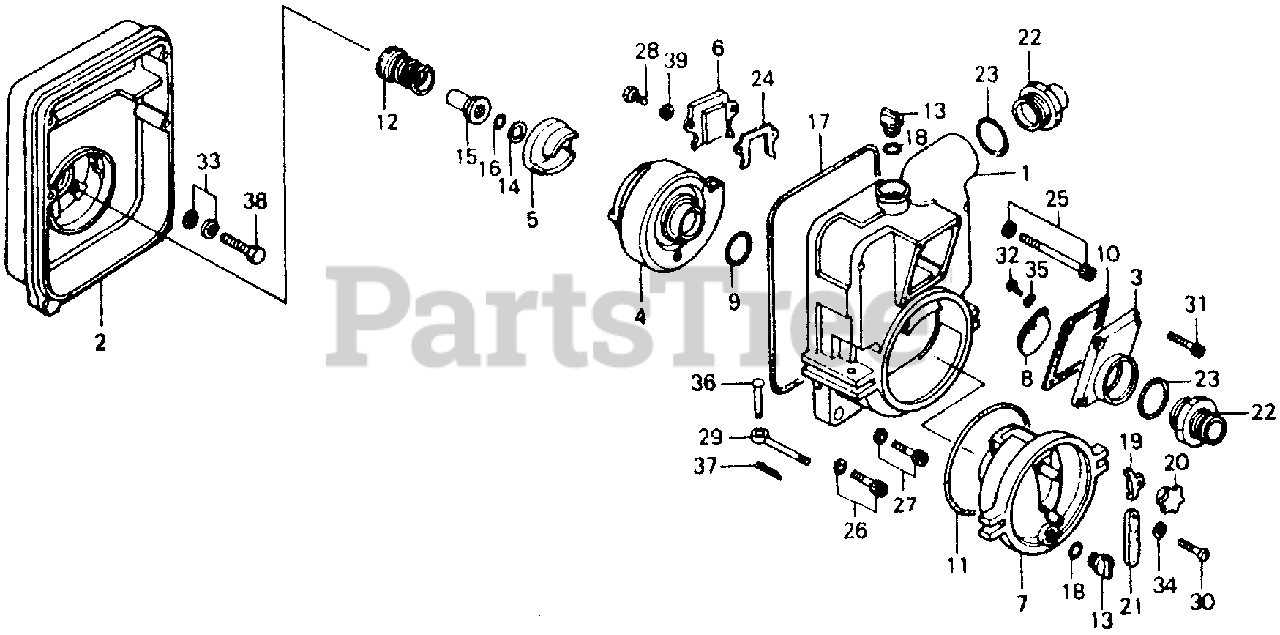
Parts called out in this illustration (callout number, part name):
1	CASING (NOT AVAILABLE)
2	COVER, CASING
3	COVER, SUCTION (NOT AVAILABLE)
4	CASING, VOLUTE (NOT AVAILABLE)
5	IMPELLER (NOT AVAILABLE)
6	PLATE, PARTITION
7	COVER, DRAIN
8	VALVE, CHECK (NOT AVAILABLE)
9	O-RING (75X3.2)
10	GASKET, SUCTION COVER (NOT AVAILABLE)
11	O-RING, DRAIN COVER
12	SEAL, MECHANICAL
13	CAP, FLOODING
14	WASHER, IMPELLER ADJUSTING (NOT AVAILABLE)
14	LINER, IMPELLER ADJUSTING (NOT AVAILABLE)
15	SLEEVE (NOT AVAILABLE)
16	O-RING (19.8X2.4)
17	O-RING, CASING
18	O-RING (30.8MM)
19	PLATE, DRAIN COVER PUSH
20	HANDLE, DRAIN COVER SETTING (NOT AVAILABLE)
21	HANDLE, DRAIN COVER (NOT AVAILABLE)
22	NIPPLE, SUCTION (NOT AVAILABLE)
23	O-RING (79.4X3.1)
25	BOLT, SOCKET SEAL
26	BOLT, SOCKET SEAL
27	BOLT, SOCKET
28	BOLT, HEX. (8X20)
29	BOLT, HINGE
30	SCREW, HANDLE SETTING
31	BOLT, SOCKET (8X28)
32	SCREW, PAN (5X10)
33	WASHER, SEAL
34	WASHER, SPRING (8MM)
35	WASHER, PLAIN (5MM)
36	PIN, HINGE (NOT AVAILABLE)
37	PIN, COTTER (4.0X30)
38	BOLT, HEX. (8X25)
39	WASHER, SPRING (8MM)
